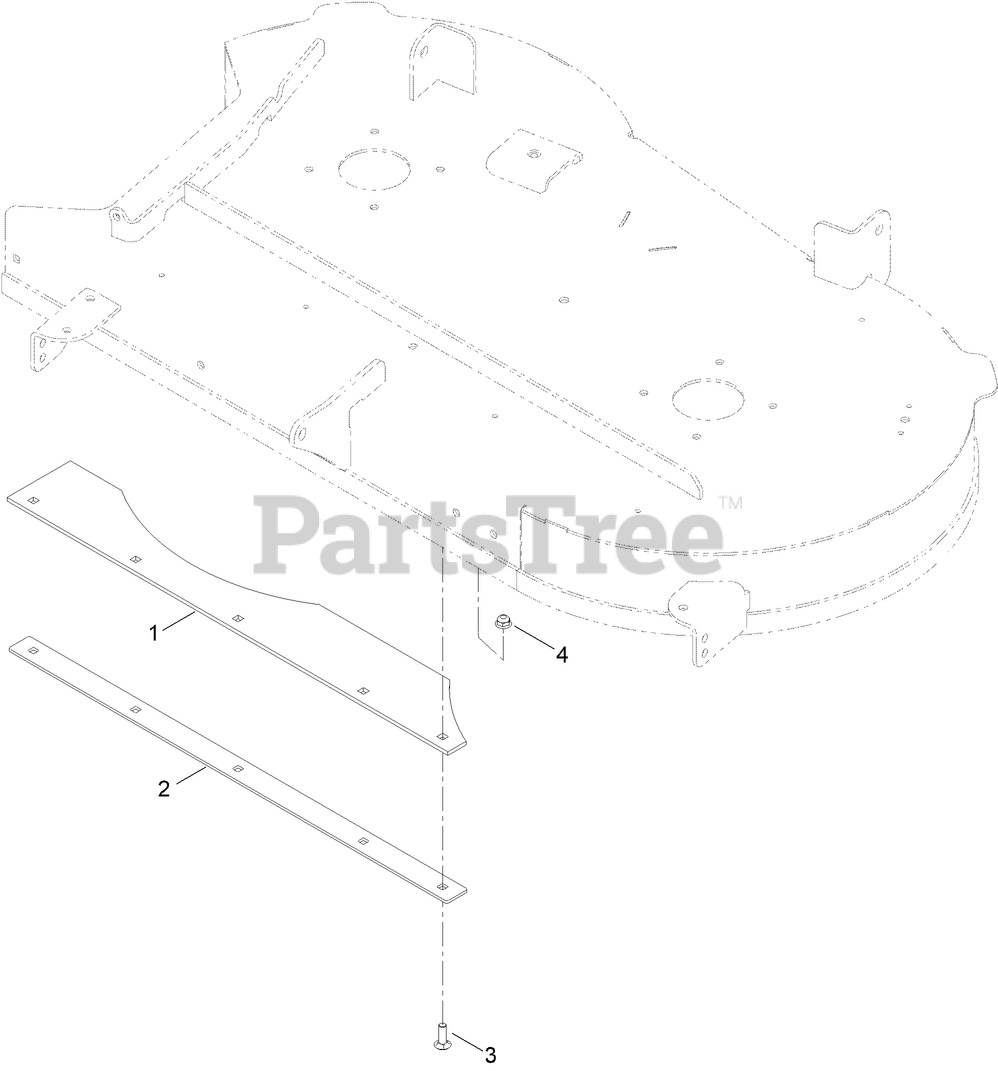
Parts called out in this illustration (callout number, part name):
1	SKIRT-RUBBER
2	PLATE-SKIRT
3	SCREW-CARR
4	NUT-HF
